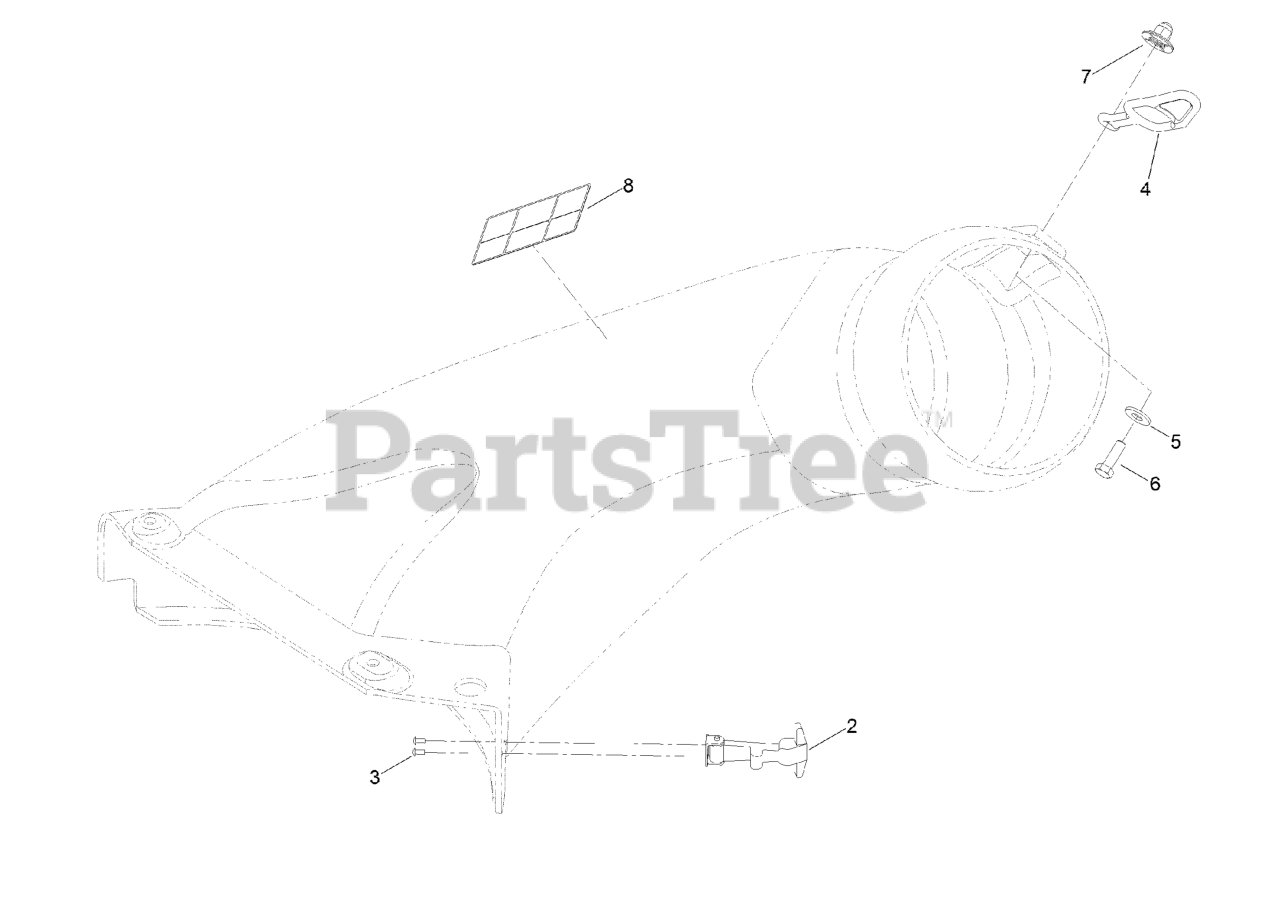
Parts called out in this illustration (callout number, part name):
2	HANDLE ASM
3	RIVET-POP
4	RETAINER-DUCT
5	WASHER-FLAT
6	SCREW-HH
7	NUT-IMPELLER
8	DECAL-DANGER
